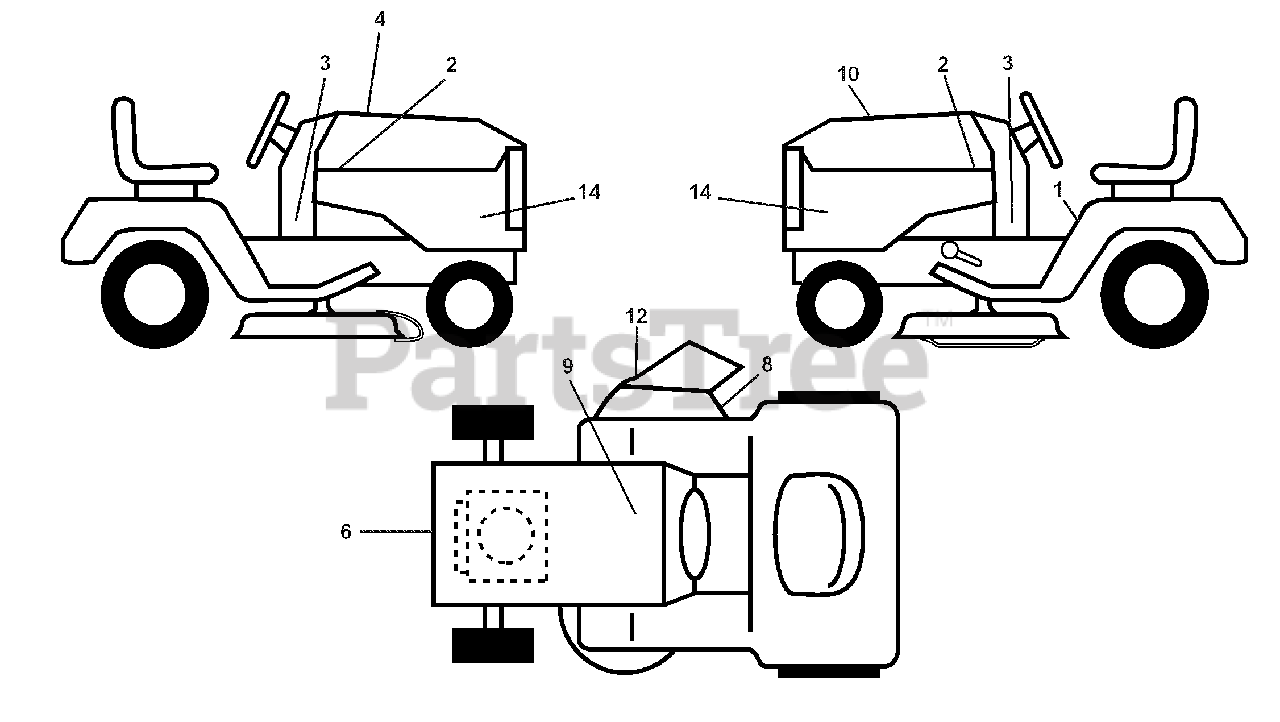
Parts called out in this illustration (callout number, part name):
1	Decal, Operator's
2	Decal, Hood Emblem
4	Decal, replacement
6	Decal, Engine HP
8	Decal, Mower Sch.
9	Decal, Battery Dnge/Poi
10	Decal, Hood Cust. Resp.
12	Decal, Mower warning Keep Hand Away
14	Decal, Panel SD
